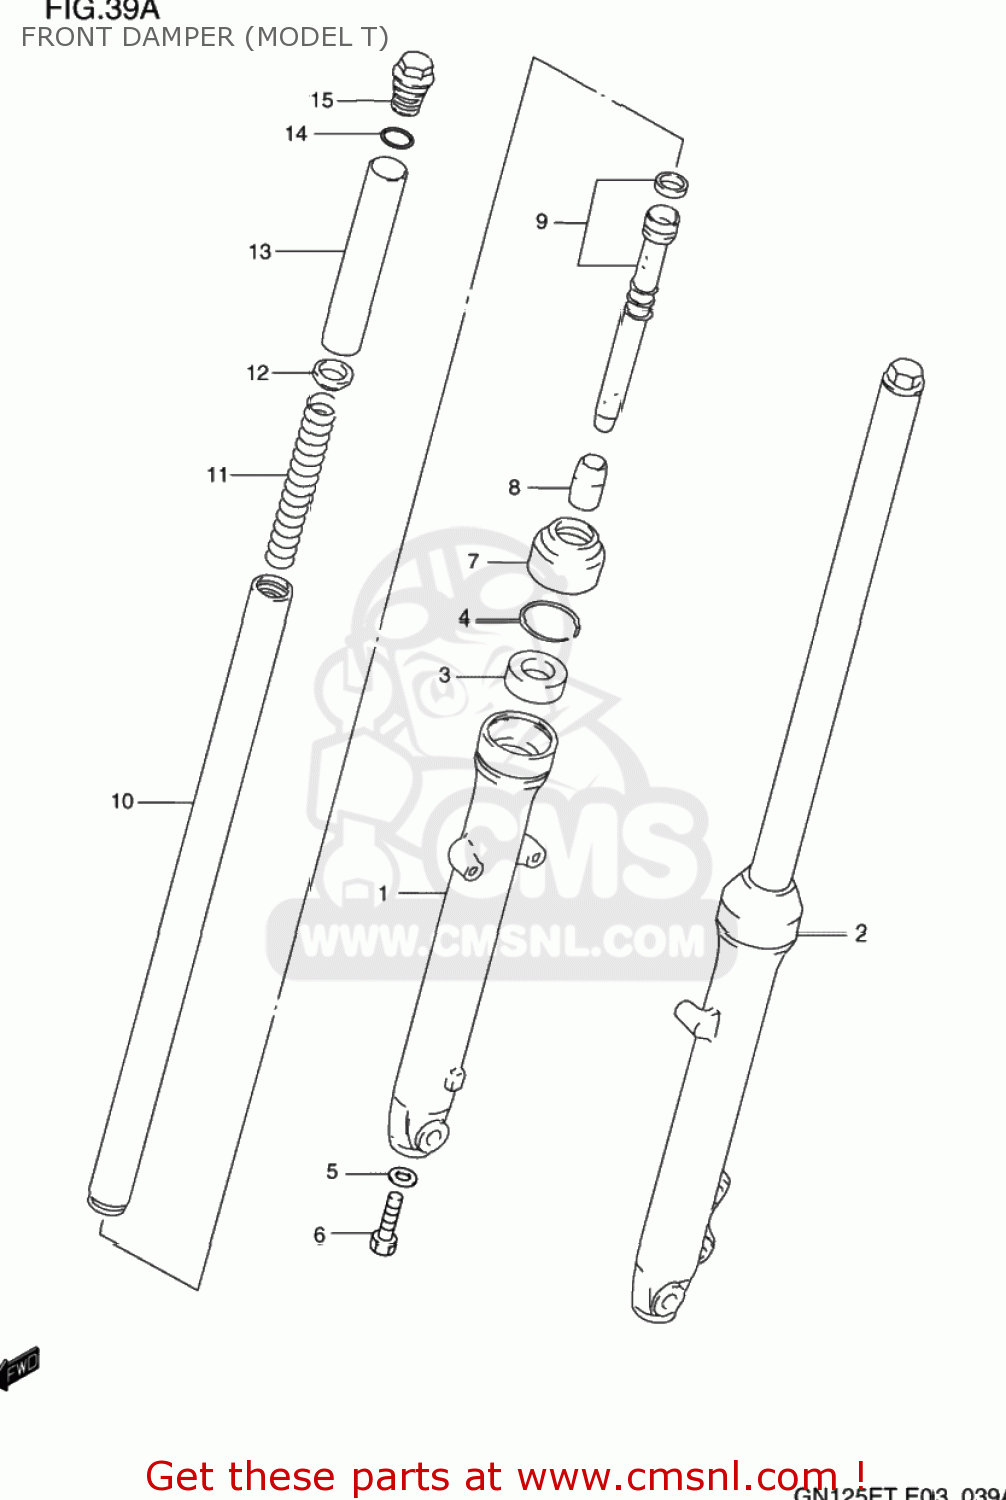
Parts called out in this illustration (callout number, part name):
1	TUBE,OUTER,R
2	TUBE,OUTER,L
3	SEAL,OIL
4	RING,SNAP
5	GASKET (NAS)
6	BOLT,FORK CYLINDER(10X25)
7	SEAL,DUST
8	PIECE,OIL LOCK
9	CYLINDER
10	TUBE,INNER
11	SPRING
12	GUIDE,SPRING COVER
13	SPACER
14	O RING
15	CAP
